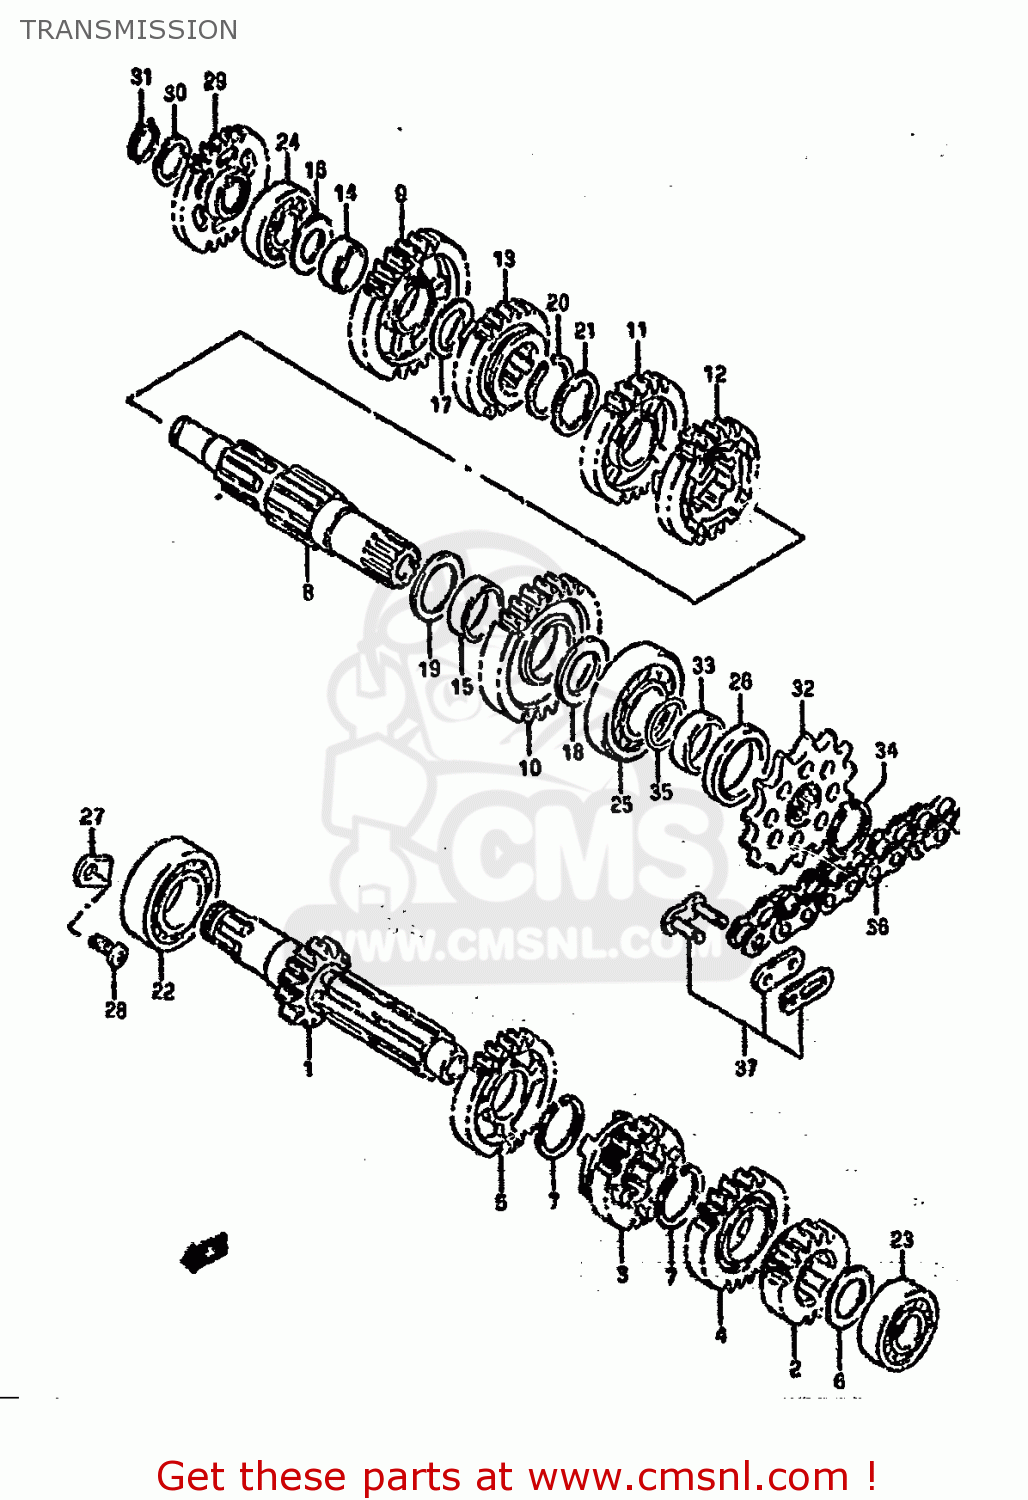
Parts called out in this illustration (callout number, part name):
1	SHAFT,COUNTER
2	GEAR,SECOND DRIVE (NT:17)
3	GEAR,3RD DRIVE
4	GEAR,4TH DRIVE(NT:19)
5	GEAR,FIFTH DRIVE
6	WASHER,THRUST
7	CIRCLIP
8	SHAFT,DRIVE
9	GEAR,1ST DRIVEN
10	GEAR,2ND DRIVEN(NT:29)
11	GEAR,THIRD DRIVEN
12	GEAR,4TH DRIVEN(NT:22)
13	GEAR,5TH DRIVEN(NT:23)
14	BUSH(20X24X10)
15	BUSH(25X28X10)
16	WASHER,THRUST
17	WASHER
18	WASHER
19	WASHER
20	CIRCLIP
21	WASHER,LOCK
22	BEARING
23	BEARING(17X40X12)
24	BEARING(17X40X12)
25	BEARING(22X56X15)
26	SEAL,OIL(28X38X6)
27	RETAINER
28	SCREW
29	GEAR,KICK STARTER IDLE
30	SHIM
31	CIRCLIP
32	SPROCKET,ENGINE
33	SPACER,ENGINE SPROCKET
34	CIRCLIP
35	O RING(D:1.9,ID:21.8)
36	CHAIN,DRIVE(520KD2X116LE)
37	JOINT ASSEMBLY,CHAIN
